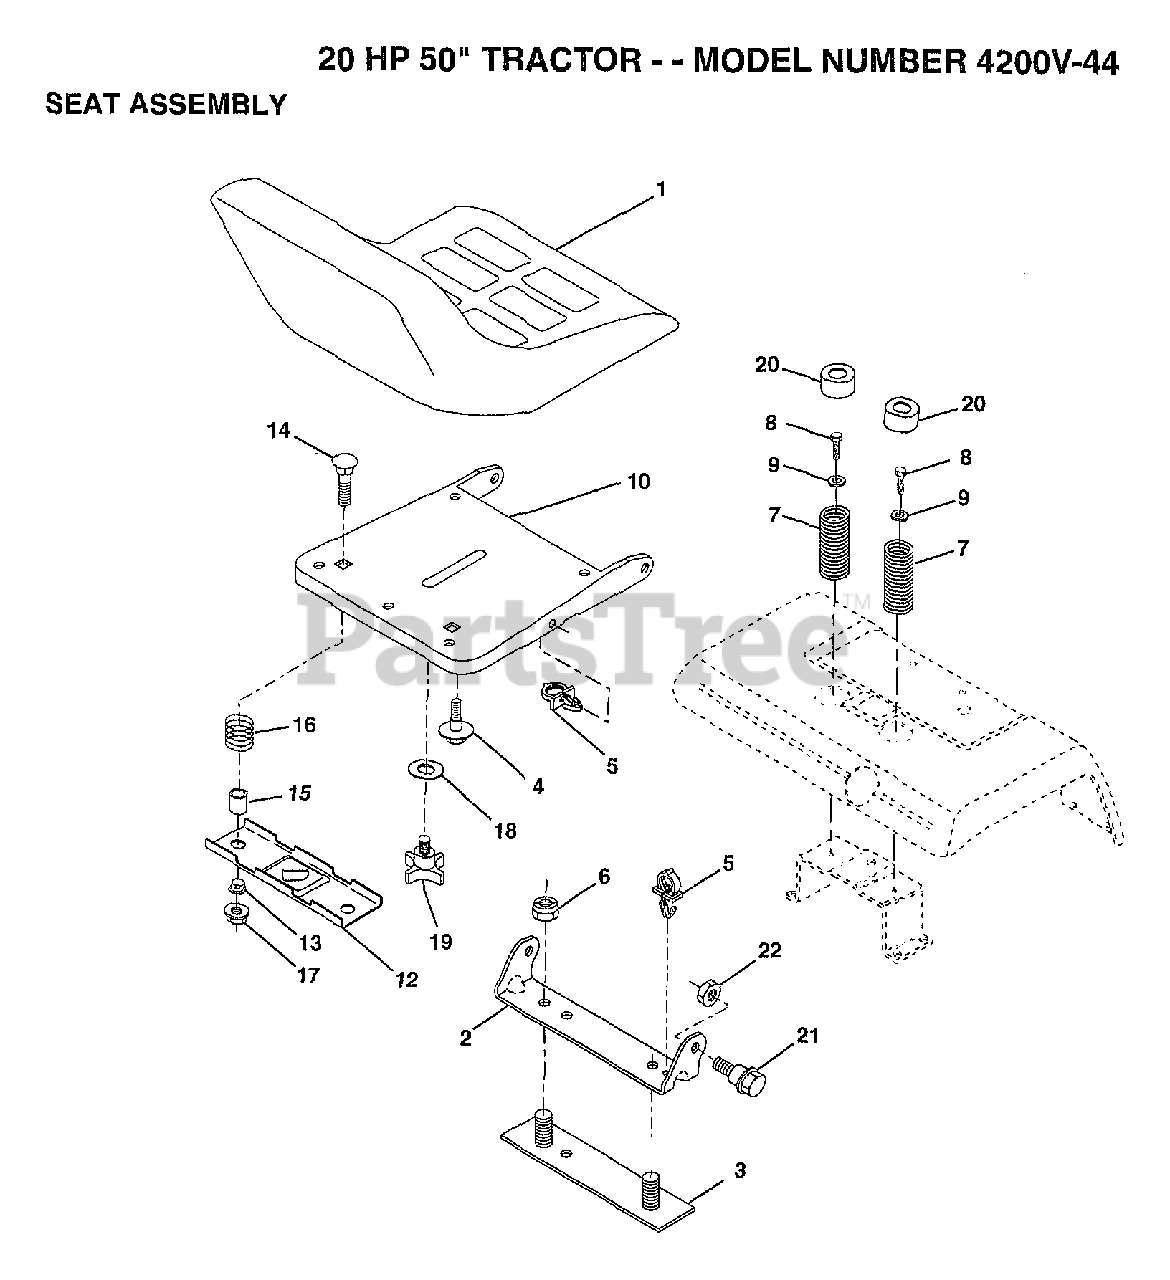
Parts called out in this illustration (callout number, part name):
2	BRACKET PVT SEAT
3	STRAP ASM FENDER
4	"BOLT,SHOULDER"
5	CLIP PUSH - IN
6	NUT
7	SPRING COMPRESSIO
8	SCREW LT
9	WASHER
12	BRKT SWITCH
13	BUSHING
15	SPACER SPLIT
16	SPRING COMPRESSED
18	WASHER
19	"KNOB 1/2"" YT"
20	CAP SPRING
21	BOLT.SHLD.5/16-18
